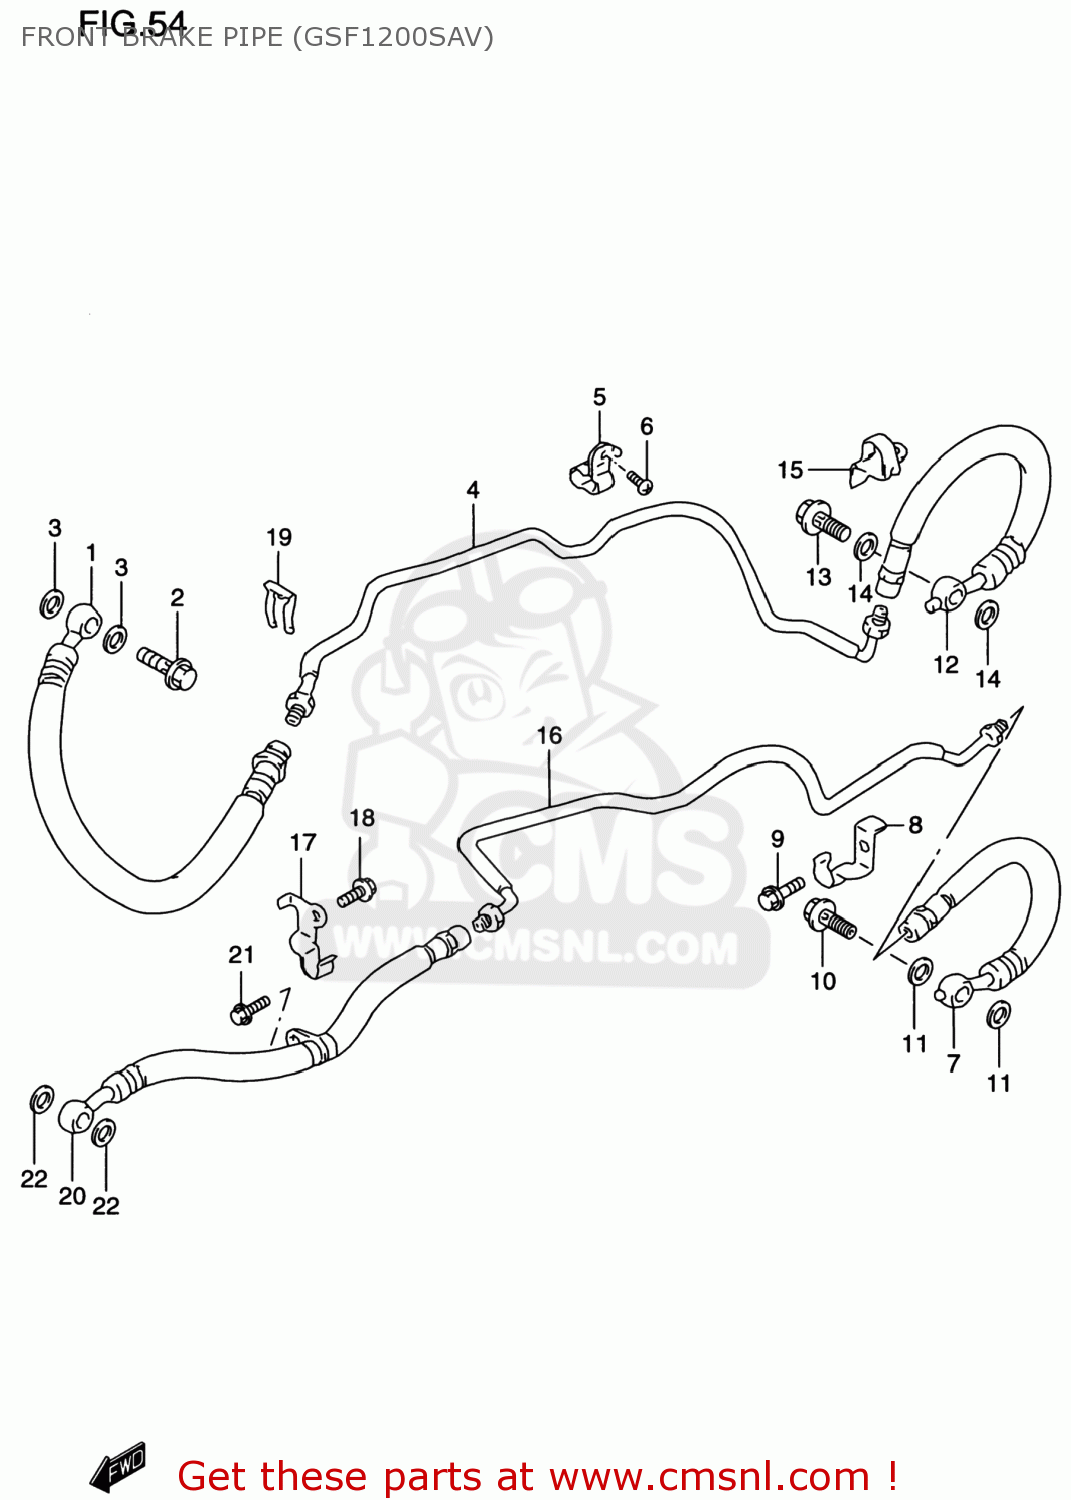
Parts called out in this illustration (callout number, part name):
1	HOSE COMP,FRONT BRAKE
2	BOLT UNION
3	WASHER(10X15X1.5)
4	PIPE,FR BRAKE NO.1
5	CLAMP,FR BRAKE PIPE
6	SCREW
7	HOSE,FR BRAKE HU OUT
8	CLAMP,FR BRAKE HOSE HU OUT
9	BOLT
10	BOLT UNION
11	WASHER(10X15X1.5)
12	HOSE,FR BRAKE HU IN
13	BOLT UNION
14	WASHER(10X15X1.5)
15	CLAMP,FR BRAKE HOSE HU IN
16	PIPE,FR BRAKE NO.2
17	CLAMP,FR BRAKE HOSE JOINT
18	BOLT
19	E RING
20	HOSE,FR BRAKE JOINT
21	BOLT
22	WASHER(10X15X1.5)
